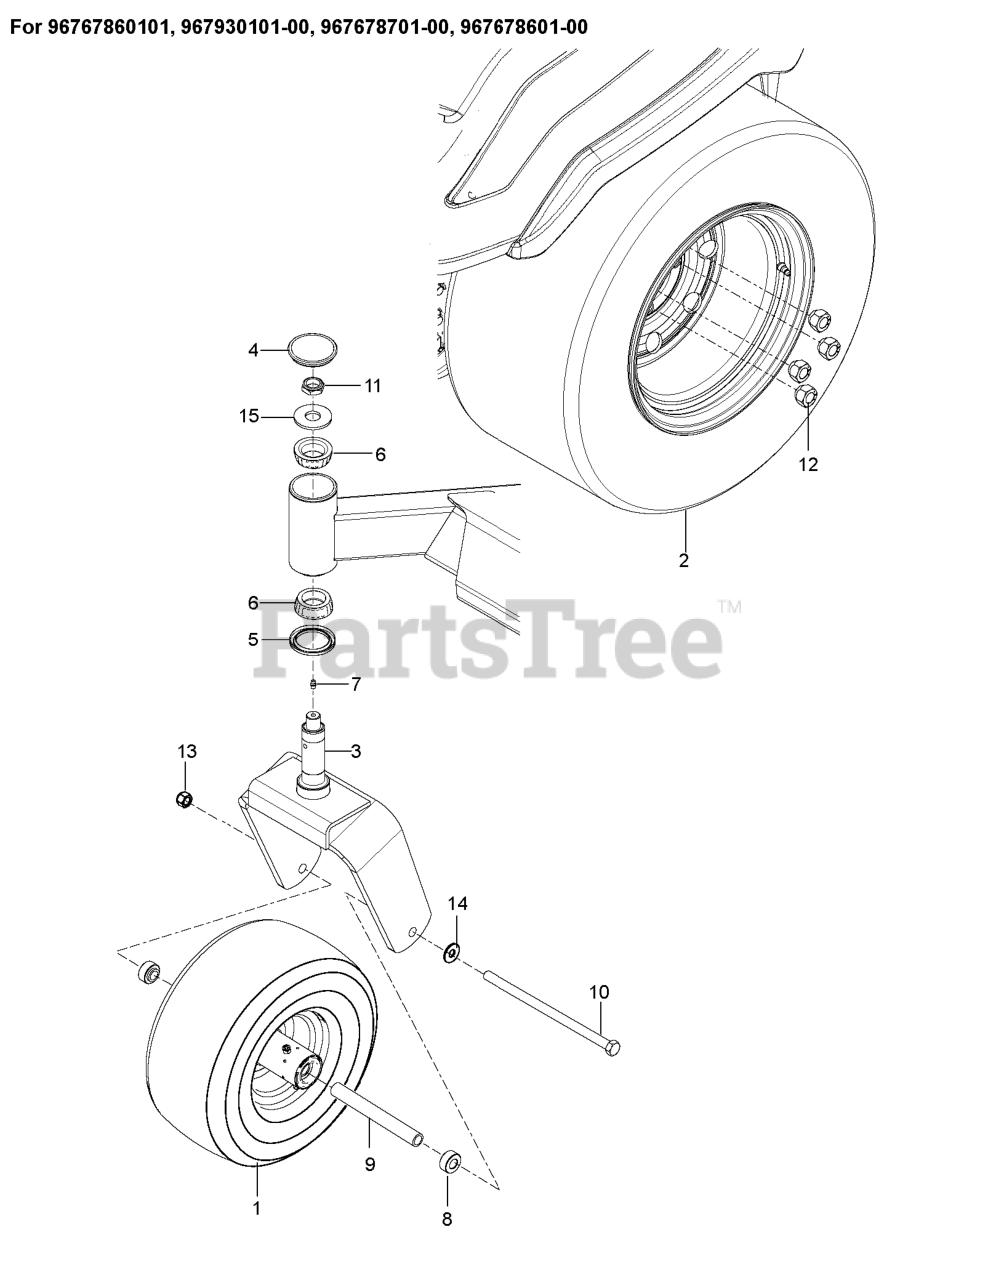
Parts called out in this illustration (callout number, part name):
1	TIRE, 13 X 6.5-6 NO FLAT
1	PZ CASTER SERVICE KIT
2	WHEEL/TIRE.ASM SILV 23X10.5-12
3	FORK.CASTER.ORANGE
5	SEAL, BEARING
6	CONE, LM67048
8	SPACER.AXLE
9	SPACER.HUB
10	HEX SCREW 1/2-13 X 9.5 GR5
11	NUT, 3/4-16 HEX THIN NYLOC ZD
12	NUT.1/2-20.UNF-2B.GR.8.YL
13	NUT. 1/2-13 HEX CNTRLK GR 5 ZD
14	WASHER 1/2" FLAT
15	WASHER, 3/4 HARDENED
